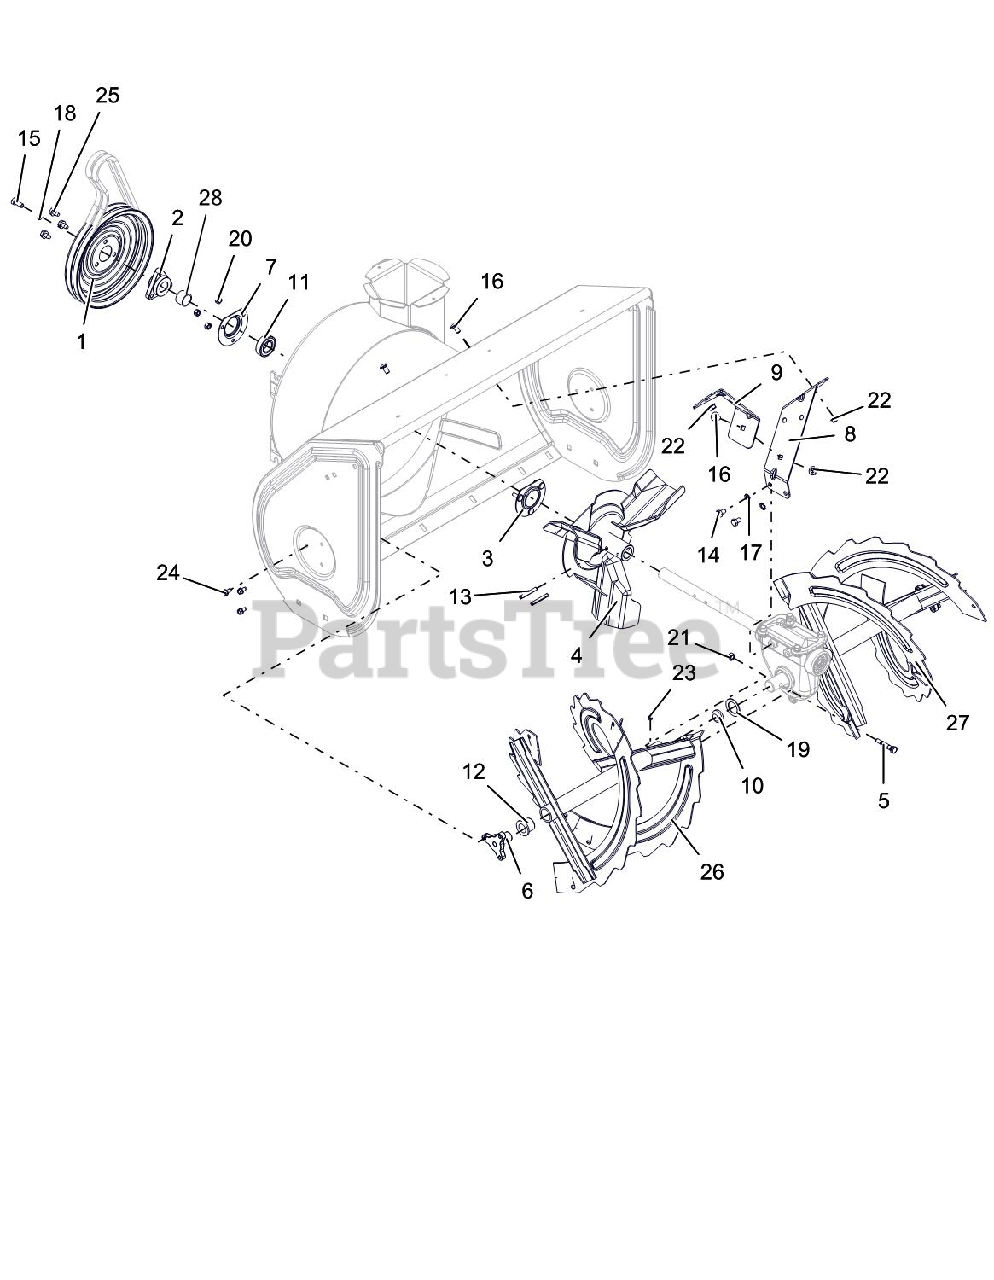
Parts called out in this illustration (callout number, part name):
1	PULLEY, SPIN FORM DUAL GROOVE
2	PULLEY HUB, D-BORE .87 DELUXE
3	BEARING FLANGE
4	IMPELLER, 3 BLADE-14"
5	SHEAR BOLT SERVICE ASSEMBLY
6	SUPPORT, RAKE BUSHING
7	BEARING FLANGE
8	BRACKET, GEARCASE SUPPORT - LH
9	BRACKET, GEARCASE SUPPORT - RH
10	PLUG, RAKE TUBE
11	BRG-BALL .876 X 1.750 X .50
12	BSHG-FLG, NY.778 ID X 1.018 OD
13	PIN-ROLL .250X1.75
14	@BLT-HEX .31-18X.50 GR5 YWZC
15	BLT-HEX .31-24X.75 YWZC GR5
16	BLT-RDHDSQSHNK.31-18X.62 YZ-LK
17	@WSHR-LK-EXT.326X.599X.031YWZC
18	WSHR-LK .312X.097 HVY YWZC
19	WSHR-FL-STL 1.010X1.505X.062YZ
20	@NUT-LK-CTR .25-20 YWZC
21	@NUT-LK-CTR .31-18 YWZC
22	@NUT-LK-TOP-FLG .31-18 YWZC
23	ZERK,FITTING .25X.125 DRIVE IN
24	SCR-TAP .25-20X.50 HWH TR YWZ
25	@SCR-TAP .31-18X.50 HWH TR YWZ
26	RAKE, RH W/ZERK - 30"
27	RAKE, LH W/ZERK - 30"
28	BSHG,SPCR .895X1.065X.693
